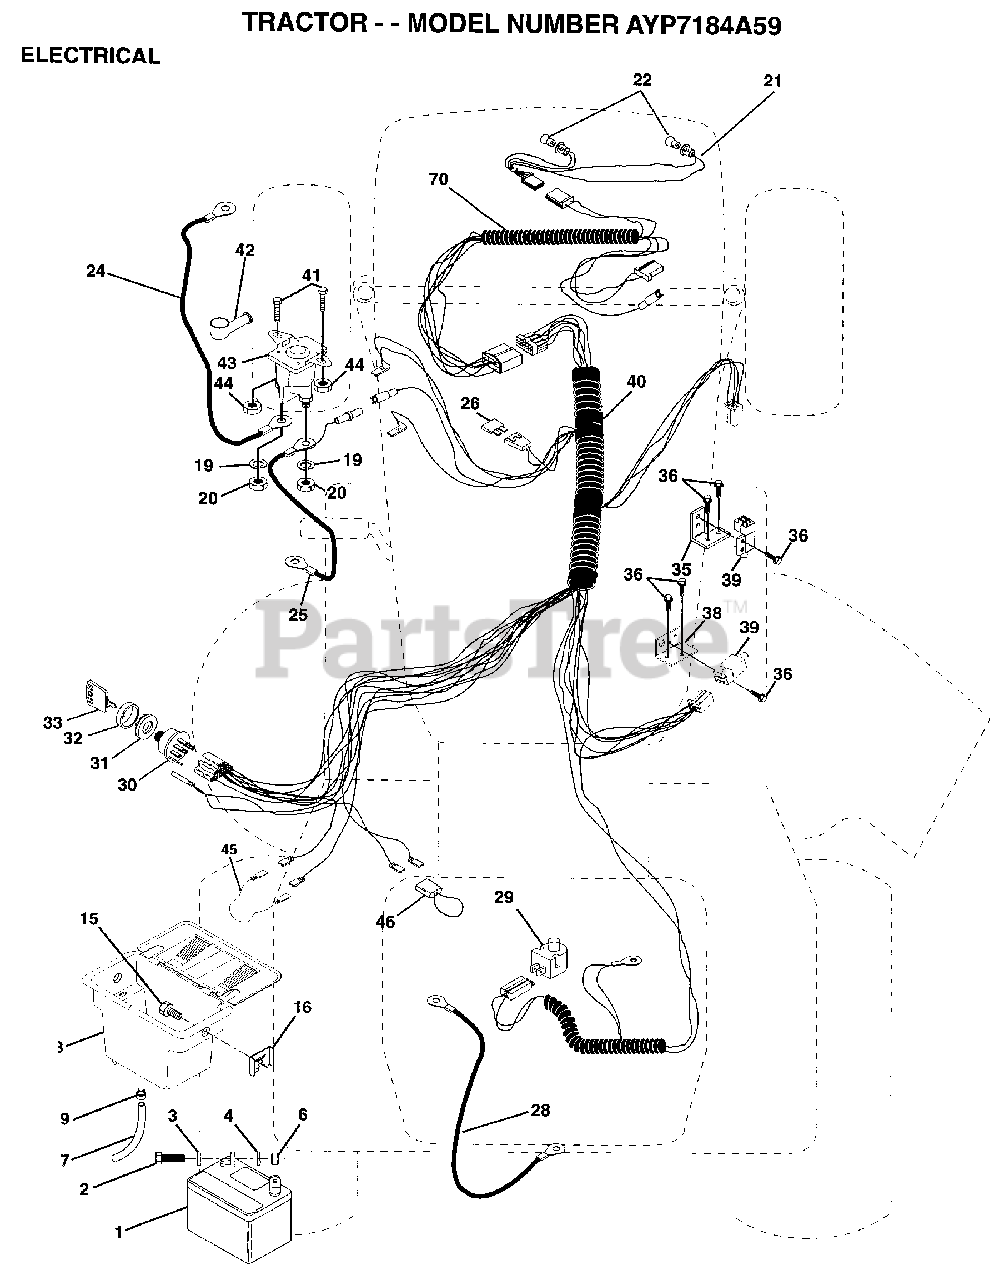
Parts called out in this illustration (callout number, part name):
2	BOLT LT
3	WASHER
4	LOCKWASHER
7	TUBE T
9	HOSE CLAMP T
15	SCREW.CAP.HEX.NYL
16	NUT.CLIP.FASTNER
20	NUT
21	"HARNESS,LIGHT SOC"
22	HEADLAMP BULB
24	CABLE-BATTERY T
25	CABLE.BTRY.6GA.RD
26	FUSE HYT
28	CABLE T
29	SWITCH SEAT
30	SWITCH IGN 4POS
31	NUT IGNITION
32	COVER KEY SWITCH
33	KEY
35	BRACKET LT
36	SCREW
38	BRACKET SWITCH IN
39	SWITCH INTERLOCKT
41	BOLT.HX.1/4-20
44	NUT
45	ADAPTER AMMETER
46	PROTECTION LOOP
70	HARNESS.ENG.LT.
